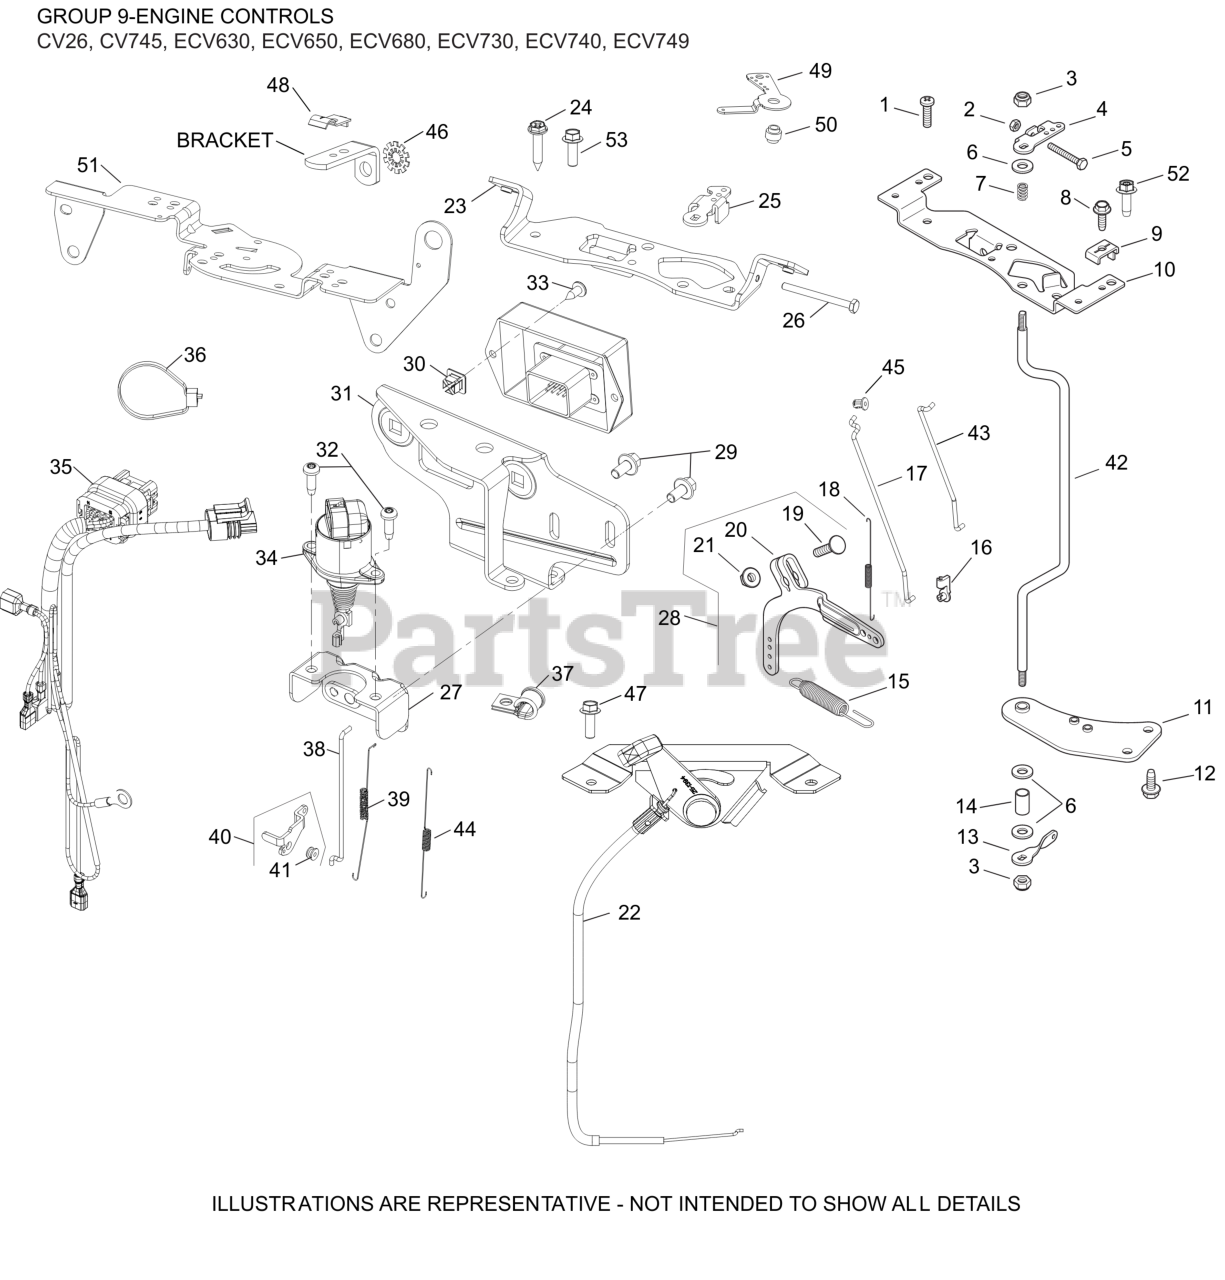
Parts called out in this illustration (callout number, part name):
3	NUT, LOCK M6X1.0
6	WASHER, FLAT 1/4"
7	SPRING, THROTTLE SHAFT
9	CLAMP, CABLE
11	BRACKET, THROTTLE SHAFT
12	SCREW, THREAD FORMING
13	LEVER, THROTTLE CONTROL
15	SPRING, GOVERNOR (GREEN)
16	BUSHING, THROTTLE LINKAGE
17	LINKAGE, THROTTLE
18	SPRING, LINKAGE
19	BOLT, RD HD SQ NECK M6X1.0X25
20	LEVER, GOVERNOR - (#2409069S)
21	NUT, FLG M6X1.0
23	BRACKET, CONTROL
25	LEVER, THROTTLE CONTROL
26	SCREW, HEX HEAD
28	LEVER, GOVERNOR ASSEMBLY
42	THROTTLE CONTROL SHAFT
46	WASHER,INT EXT TOOTH LOCK 1/4"
53	SCREW, HI-LOW
